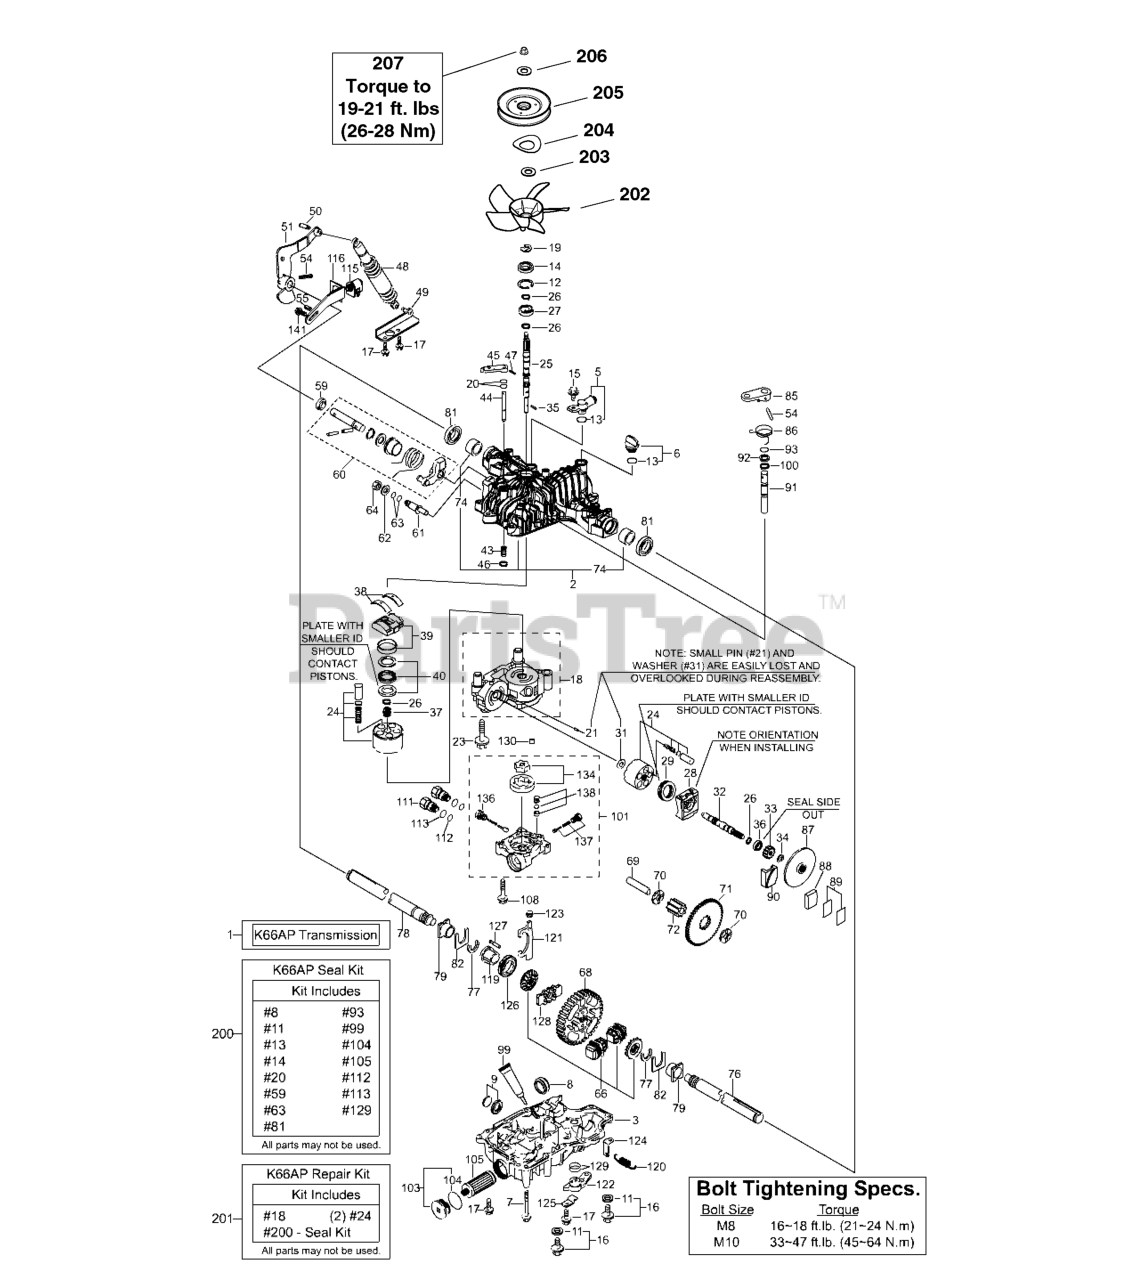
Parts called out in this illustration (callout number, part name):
1	TRANSMISSION, Tuff Torq, K66AS
2	* UPPER CASE KIT
3	* LOWER CASE
5	* FITTING KIT
6	* CAP KIT
11	WASHER SEAL 10
12	SNAP RING C 35
14	SEAL TC 153507
16	* DRAIN BOLT KIT
17	TAPPING SCREW 8 x 30
18	* CENTER CASE AB
19	E-RING
20	O-RING, 1A P10A
21	PIN 3 x 9.8
24	* CYLINDER BLOCK KIT
26	SNAP RING S15
27	BEARING 6202C3
28	MOTOR HOUSING
29	THRUST BEARING
31	WASHER 12 x 24 x 1
35	PIN 3 x 13.8
36	BEARING 6302DUC3
37	PUMP SPRING
38	THRUST METAL
39	SWASH PLATE ASSEMBLY
40	* THRUST BEARING KIT
44	BYPASS SHAFT
45	BYPASS LEVER
47	SPRING PIN 3.0A x 20
48	* SHOCK ABSORBER
51	* CONTROL LEVER
54	ROLL PIN 6 x 40
59	SEAL TC 162606
60	* CONTROL SHAFT KIT
63	O-RING 1A P14
66	* DIFFERENTIAL GEAR KIT
68	* FINAL GEAR
69	FINAL PINION SHAFT
70	WASHER 15 x 35 x 3.2
71	REDUCTION GEAR (53T)
72	FINAL PINION Gear (11T)
74	BUSHING 25.4
76	AXLE SHAFT, LEFT
77	RETAINING RING 23
78	AXLE SHAFT, RIGHT
79	BUSHING 25.4
81	SEAL S 25.4 x 42 x 8
82	THRUST WASHER
85	* BRAKE LEVER
86	* BRAKE RETURN SPRING
90	BRAKE ACTUATOR
91	BRAKE SHAFT
92	WASHER 16 x 23 x 1.6
93	O-RING 1A P12
99	* SEALANT
101	* PUMP CASE KIT (K664C & E)
103	* CAP KIT
115	* SWITCH 6440-11 DELTA
116	* SWITCH PLATE
120	DIFFERENTIAL RETURN SPRING
121	DIFFERENTIAL LOCK FORK
122	DIFFERENTIAL LOCK LEVER
123	* LEVER PIVOT
124	SPRING HOOK
126	DIFFERENTIAL LOCK SLIDER
127	* DIFF LOCK PIN
128	* DIFF LOCK PLATE
129	0-RING 1A G25
134	* ROTOR SET
136	CHARGE RELIEF VALVE
137	IMPLEMENT RELIEF VALVE
138	3RD CHECK VALVE
141	TAPPING SCREW 8 x 20
200	* KIT, Seal
201	* REPAIR KIT
203	WASHER, Flat
204	WASHER, Wave, 0.65" ID
206	WASHER, Flat
207	NUT, Hex Flange, M10-1.5, Nylon Insert
